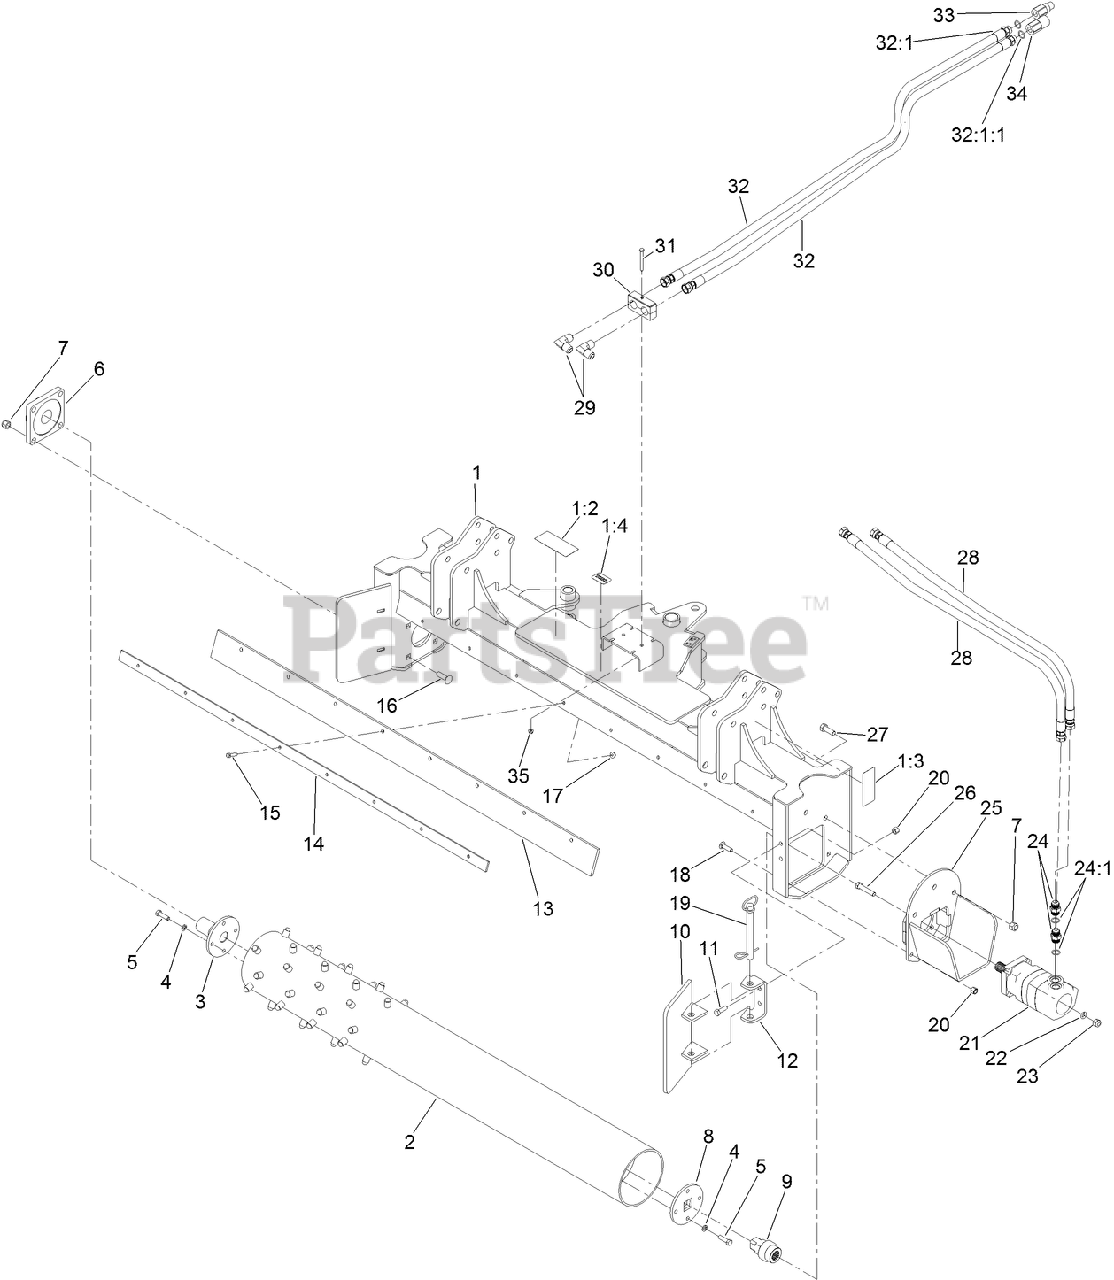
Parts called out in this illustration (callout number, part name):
1	FRAME ASM
1:2	DECAL-DANGER
1:3	DECAL-WARNING
1:4	DECAL
2	DRUM-POWER RAKE
3	PLATE-DRUM
4	SCREW-HH
5	SCREW-HH
6	BEARING-FLANGED
7	NUT-LOCK, NI
8	HUB-ADAPTER
9	ADAPTER-MOTOR
10	BRACKET-GUIDE
11	SCREW-HH
12	MOUNT-WING
13	DEFLECTOR
14	STRAP-DEFLECTOR
15	SCREW-HH
16	BOLT-CARR
17	NUT-HF, NI
18	SCREW-CARR
19	PIN-HITCH
20	NUT-LOCK, NI
21	HYDRAULIC MOTOR ASM
22	WASHER-LOCK
23	NUT-LOCK, NI
24	FITTING-STRAIGHT
24:1	O-RING
25	MOUNT-HYD MOTOR
26	SCREW-HH
27	SCREW-HH
28	HOSE ASM
29	FITTING-ELBOW
30	CLAMP-HOSE
31	SCREW-HH
32	HOSE ASM
32:1	FITTING-STRAIGHT
32:1:1	O-RING
33	FITTING-HYD
34	FITTING-HYD
35	NUT-HF, NI
